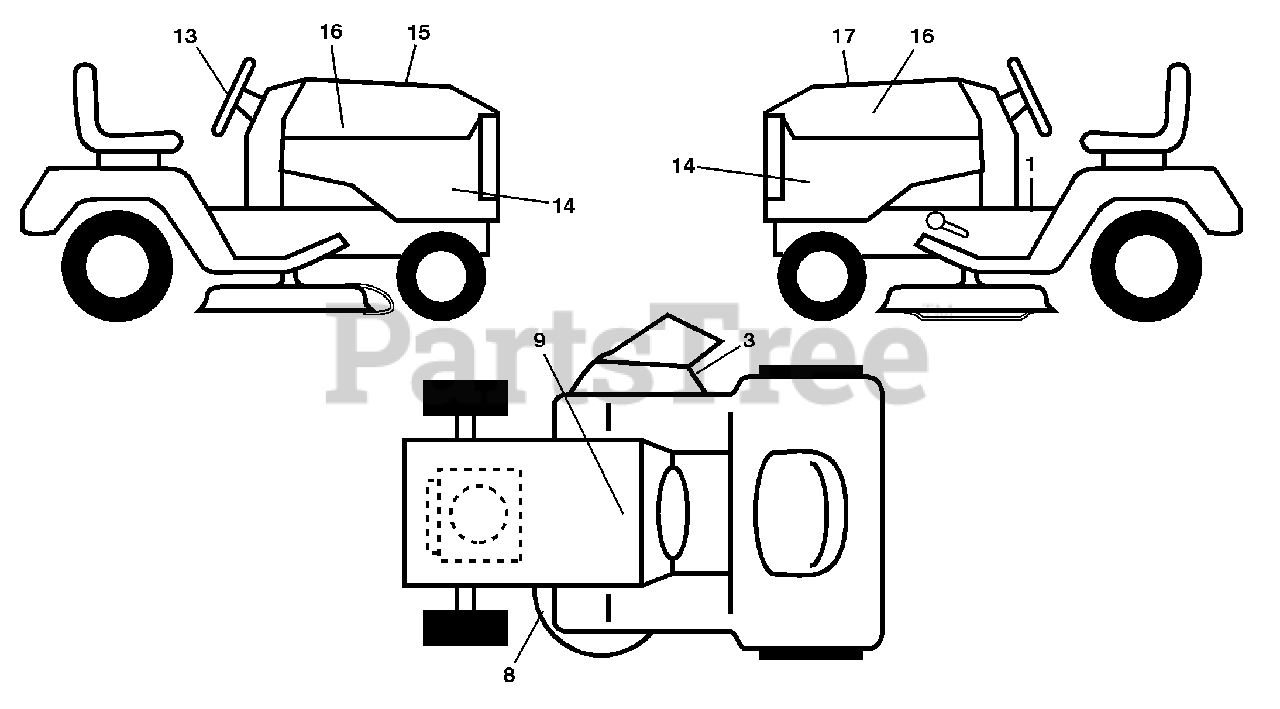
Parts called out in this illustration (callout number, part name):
1	Decal, Warning
3	Decal, Warning
8	Decal, Mower Sch.
9	Decal, Battery Dnge/Poi
13	Decal, Steering Whl
14	Decal, Panel Side
15	Decal, Cust. Resp.
16	Decal, Hood Logo
17	Decal, Replacement
17	Decal, Bypass
17	Pad, Footrest, LH
17	Pad, Footrest, RH
17	Manual, Owner's
